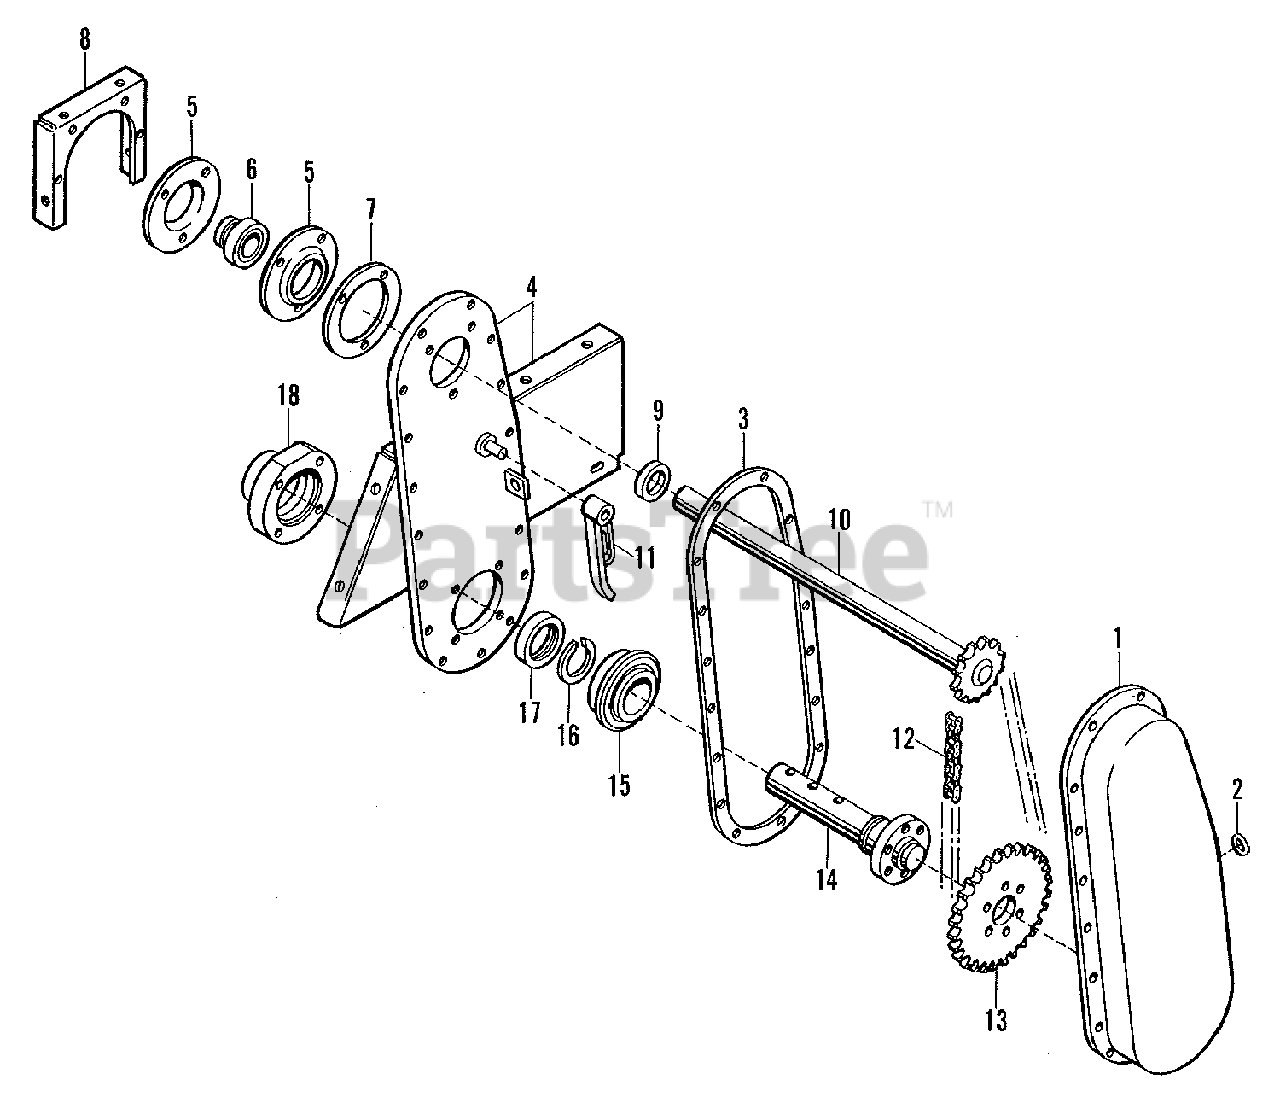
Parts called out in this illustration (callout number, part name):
1	COVER, Chain Case
1	CAPSCREW, 5/16NC x 1
1	CAPSCREW, 5/16NC x 1/2
1	LOCKWASHER, 5/16
1	NUT, 5/16NC
1	WASHER, Plain, 1/2 x 1 x 14 Ga.
1	CAPSCREW, Full Thread, 1/2NC x 3
1	NUT, Jam, 1/2NC
3	GASKET, Cover
4	PLATE ASSEMBLY, Chaincase
5	FLANGE, Bearing
5	CAPSCREW, 3/8NC x 3/4
5	LOCKWASHER, 3/8
7	GASKET, Flange
8	BRACKET, Angle Clip
10	SHAFT, Input (w/Splines)
11	TIGHTENER, Chain
12	CHAIN ASSEMBLY, Roller, #80
13	SPROCKET (18T)
13	CAPSCREW, 3/8NC x 1-1/4
13	LOCKWASHER, 3/8
14	SHAFT, Output
16	RING, Retaining
18	HOUSING, Bearing
18	CAPSCREW, 3/8NC x 1-1/2
18	LOCKWASHER, 3/8
